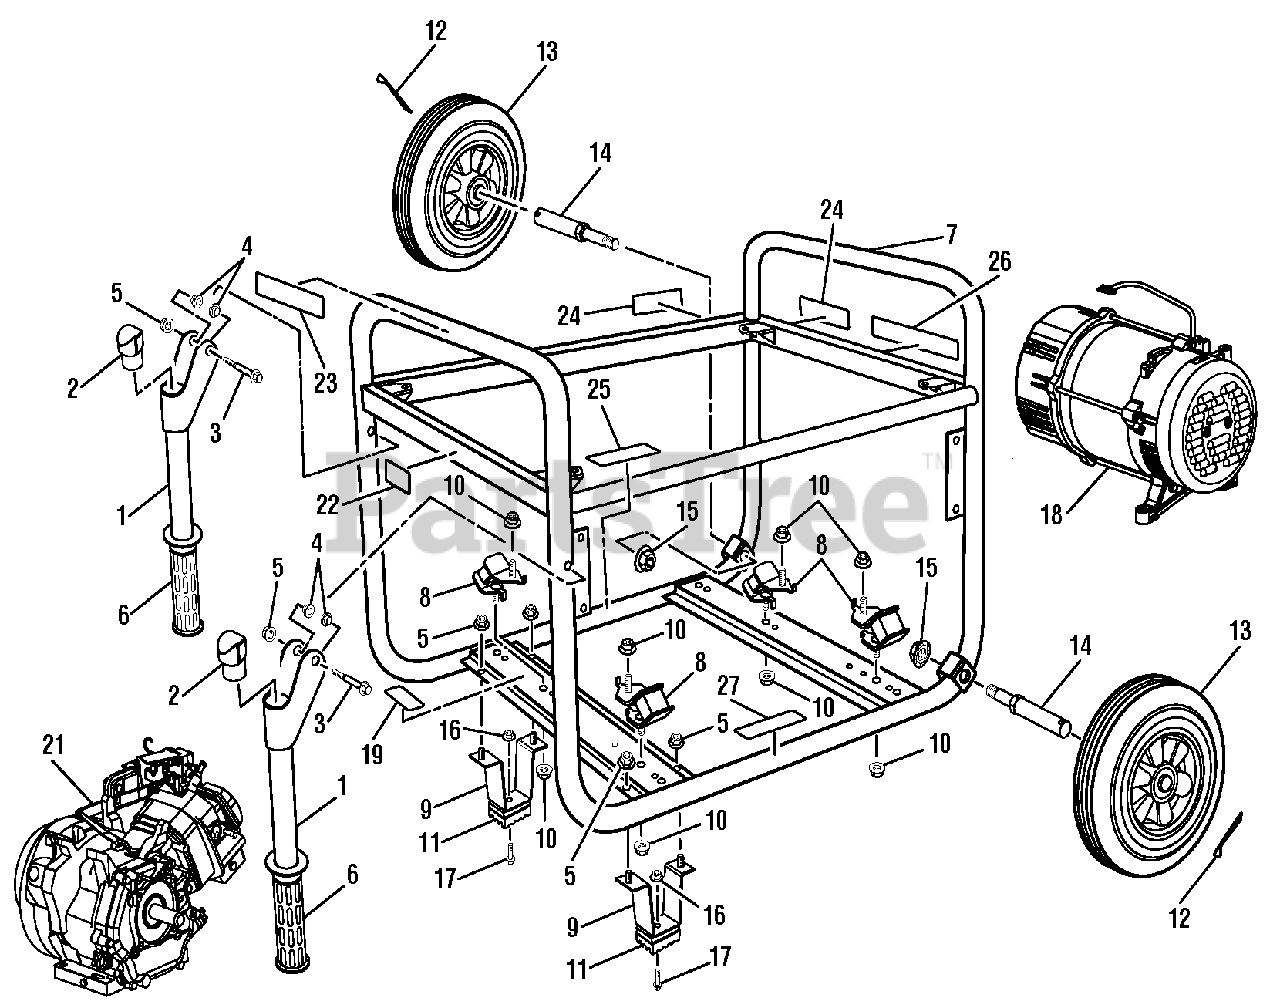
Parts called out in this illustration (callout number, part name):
1	Handle Bar Assembly
2	Handle Bar Plug
3	Bolt (M8 x 45 mm)
4	Handle Bar Insert
6	Handle Grip
8	Motor Mount
9	Foot Bracket
10	Nut (M10)
11	Rubber Foot
12	Cotter Pin (3 mm)
13	Wheel (10 in.)
15	Nut (M12, Flange Hd.)
16	Flange Nut (M6)
17	Screw (M6 x 25)
18	Generator Head Assembly
19	Data Label
20	Ground Label
22	Fuel Valve Label
23	Fire Danger Label
24	Hot Surface Warning Label
25	Combustion Warning Label
26	Ground Warning Label
27	Lubricant Label
